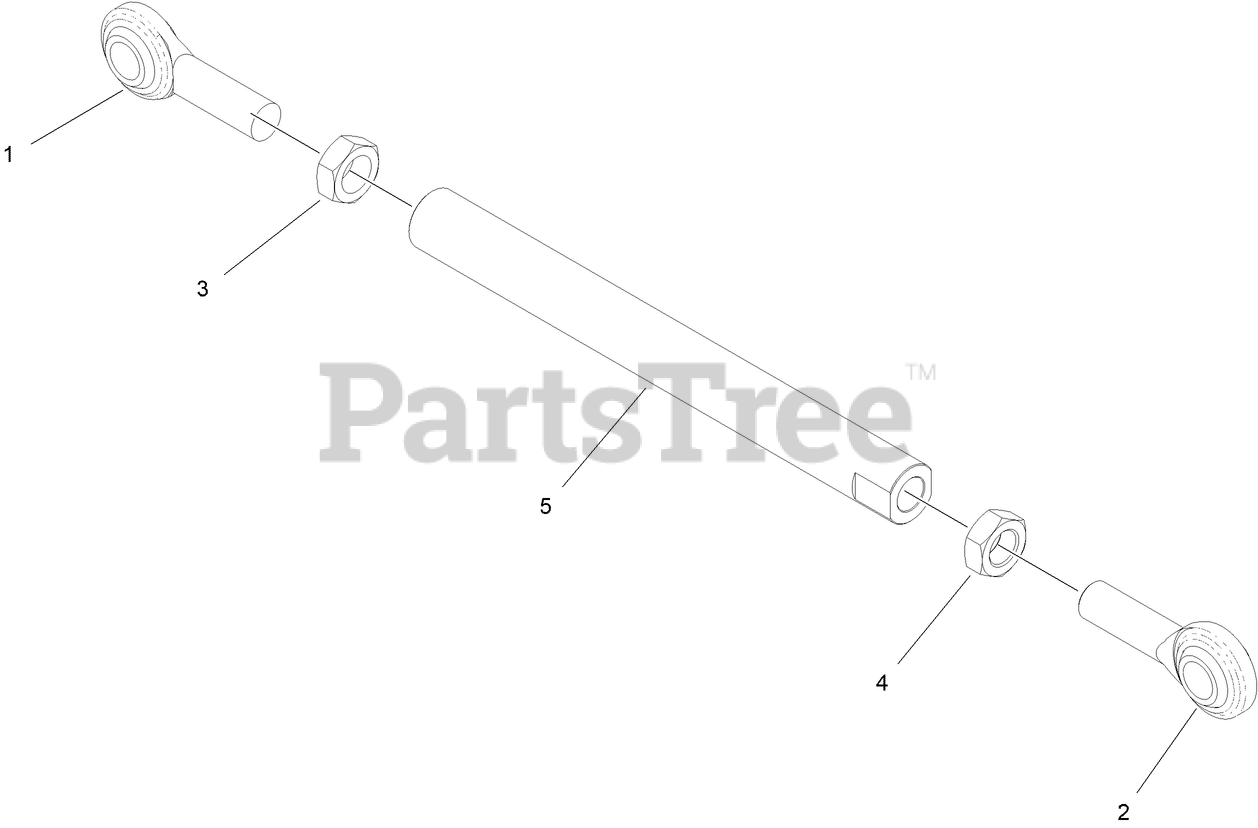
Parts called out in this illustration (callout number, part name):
1	BALLJOINT-SPHERICAL
2	BALLJOINT-SPHERICAL
3	NUT-JAM
4	NUT-JAM
5	LINK-HEIGHT OF CUT
